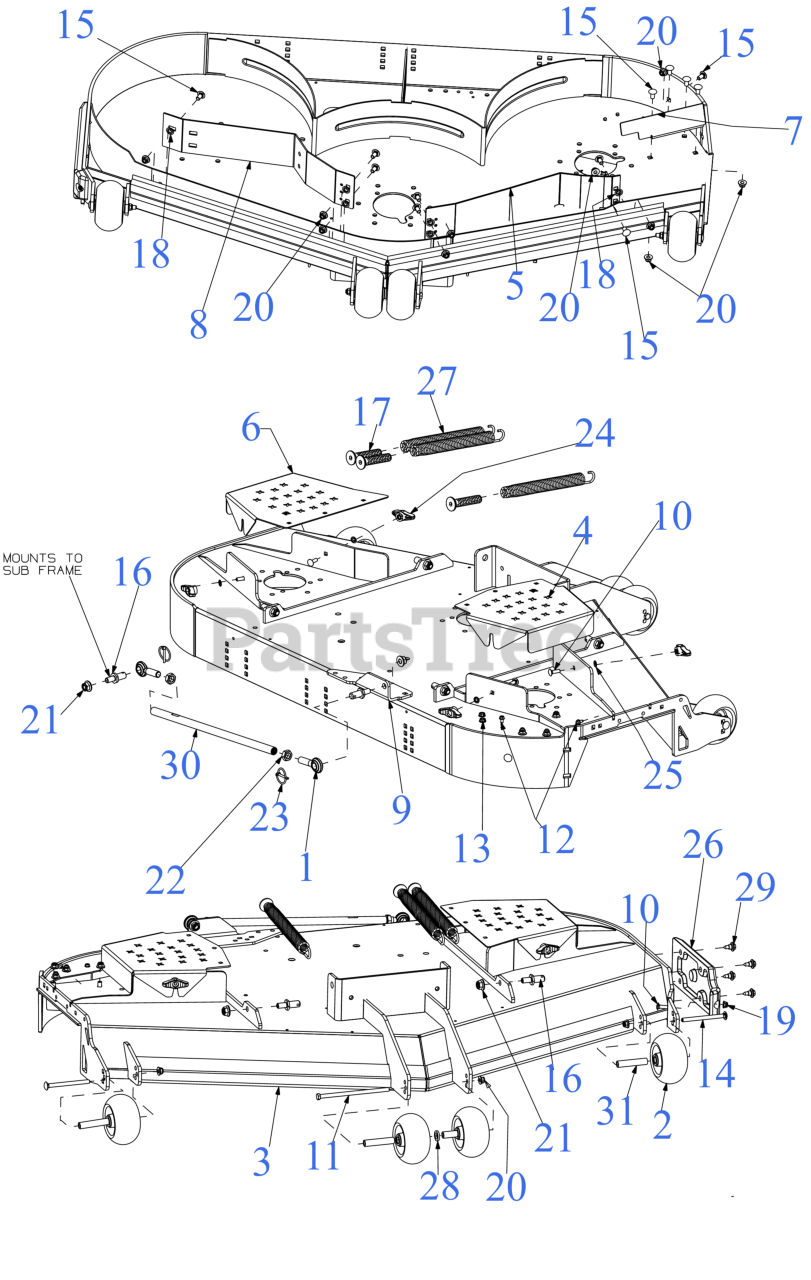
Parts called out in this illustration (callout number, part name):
1	MALE ROD END
2	5" DIA DECK WHEEL COMPLETE
3	60" FAB DECK SHELL
4	DECK BELT COVER
5	DECK BAFFLE
6	BELT COVER
8	DECK BAFFLE
9	DECK BELT GUIDE BRACKET
10	CARRIAGE BOLT 5/16-18 x 1.00
11	SCREW 3/8-16 x 7.25 GR5
12	SCREW 1/4-20 X.500
13	SCREW 5/16-18 x .500
14	CARRIAGE BOLT 3/8-16 x 4.25 GR5
15	CARRIAGE BOLT 3/8-16 x .75
17	SPRING INSERT SCREW
19	FLANGE LOCK NUT 5/16-18
22	HEX JAM NUT 5/8-18
23	LYNCH PIN .1875
24	WING KNOB 5/16-18
26	DECK SKID PLATE (LH)
27	EXTENTION SPRING 1.20 x 11.35
28	FLAT WASHER .632X1.00X.16
29	SHOULDER SCREW .43X.29X5/16-18 TT
30	TUBE .565 X .750 X 18.75"LG
31	WHEEL SPACER .38ID x 3.04LG
